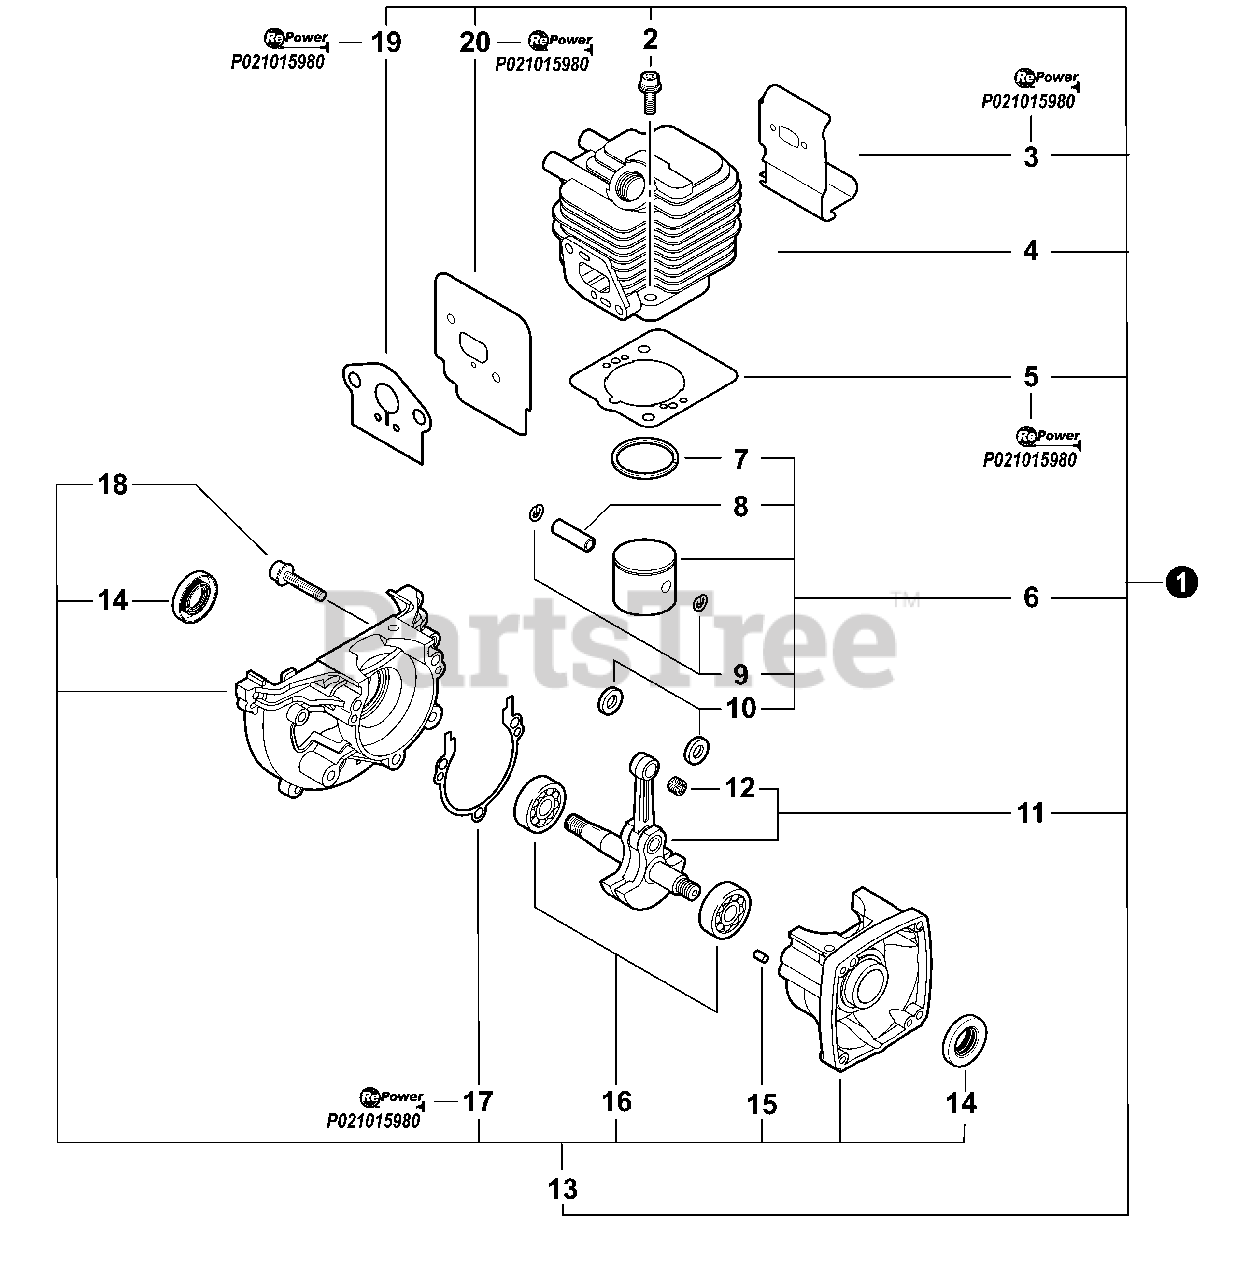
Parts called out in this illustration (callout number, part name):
1	SHORT BLOCK
2	BOLT 5×22
3	HEAT SHIELD, EXHAUST
4	CYLINDER
5	GASKET, CYLINDER
6	PISTON KIT
7	RING, PISTON
8	PIN, PISTON 8
9	RING, SNAP
10	WASHER, THRUST
11	CRANKSHAFT ASSY
12	BEARING, NEEDLE 8
13	CRANKCASE KIT
14	SEAL, OIL 12
15	PIN, LOCATING 4×8
16	BEARING, BALL - 6201 C3
17	GASKET, CRANKCASE
18	BOLT 5×28
19	GASKET, INTAKE
20	HEAT SHIELD, INTAKE
